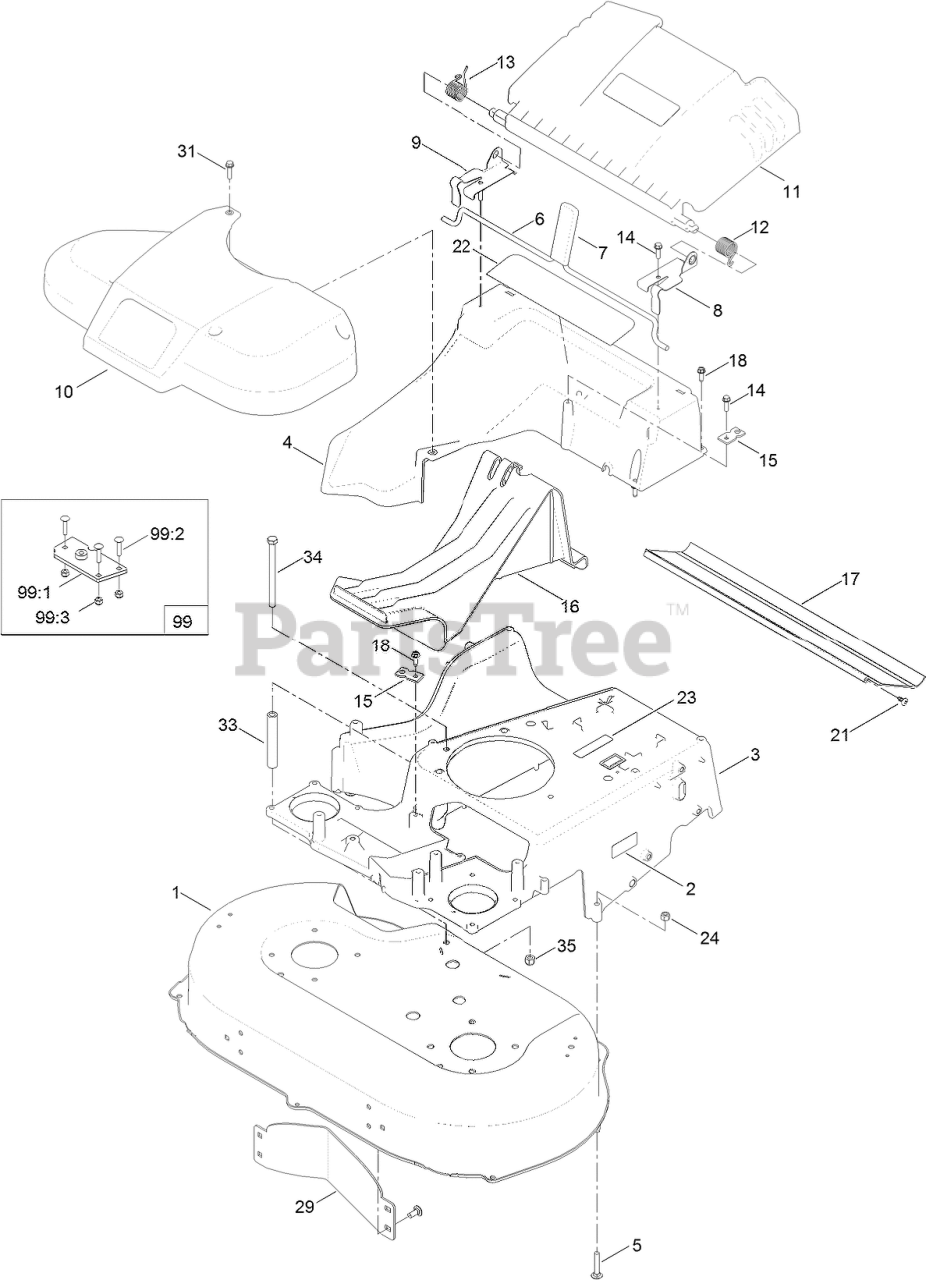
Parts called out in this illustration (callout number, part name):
1	HOUSING ASM
2	DECAL-LOCATION, SERVICE DEALER
3	FRAME
5	SCREW-CARR
6	ROD-RELEASE, HANDLE
7	GRIP-LEVER
8	BRACKET-DOOR, LH
9	BRACKET-DOOR, RH
10	BELT COVER ASM
11	REAR DEFLECTOR ASM
12	SPRING-TORSION
13	SPRING-TORSION
14	SCREW-HWH
15	BRACKET-CABLE, TRACTION
16	PLUG-MULCH
17	SHIELD-TRAILING
18	SCREW-HWHTF
21	SCREW-PTH
22	DECAL-POSITION, HANDLE
23	DECAL-ARRESTER, SPARK
24	NUT-LOCK, NI
29	BAFFLE-CONTROL
31	SCREW-HWHTF
33	SPACER-SHIELD
34	SCREW-HH
35	NUT-LOCK, NI
99	FRAME PLATE KIT
99:1	PLATE-FRAME
99:2	SCREW-CARR
99:3	NUT-LOCK, NI
